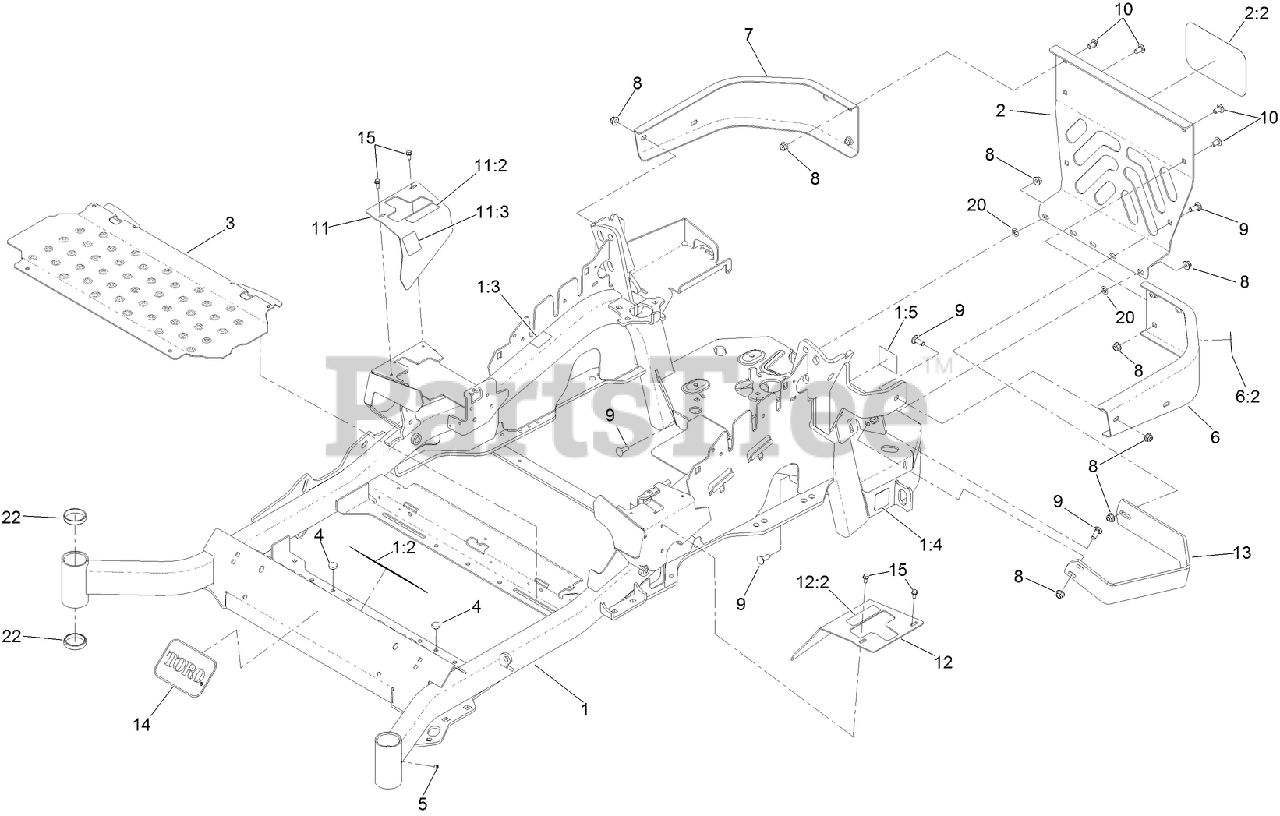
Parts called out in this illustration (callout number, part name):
1	MAINFRAME ASM
1:2	DECAL-DANGER
1:3	DECAL-WARNING
1:4	DECAL-HAZARD, PINCHED FINGER
1:5	DECAL-SPARK ARRESTER
2	REAR GUARD ASM
2:2	DECAL
3	FLOORPAN
4	BUMPER
6	LH BUMPER ASM
6:2	DECAL-WARNING
7	BUMPER-RH
8	NUT-HF, NI
9	SCREW-CARR
10	SCREW-CARR
11	RH MOTION CONTROL COVER ASM
11:2	DECAL-CONTROL, MOTION
11:3	DECAL-PARK BRAKE, CE
12	LH MOTION CONTROL COVER ASM
12:2	DECAL-CONTROL, MOTION
13	GUARD-MUFFLER
14	DECAL
15	SCREW-HWH
20	NUT-PUSH
22	CUP-BEARING
